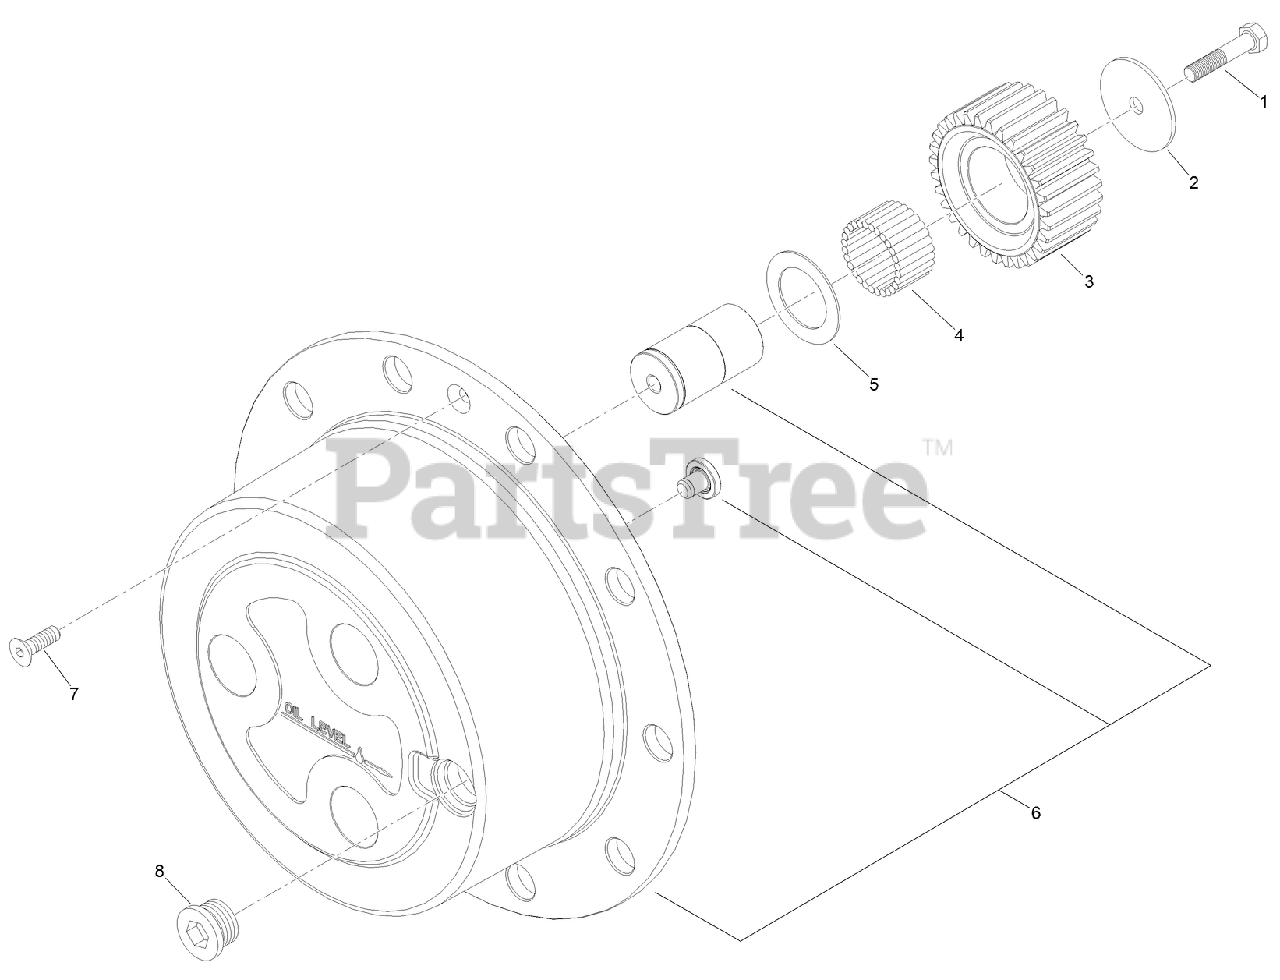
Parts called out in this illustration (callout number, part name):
2	WASHER
4	BEARING-NEEDLE (BY TENS)
5	WASHER
6	PLANETARY CARRIER ASM
